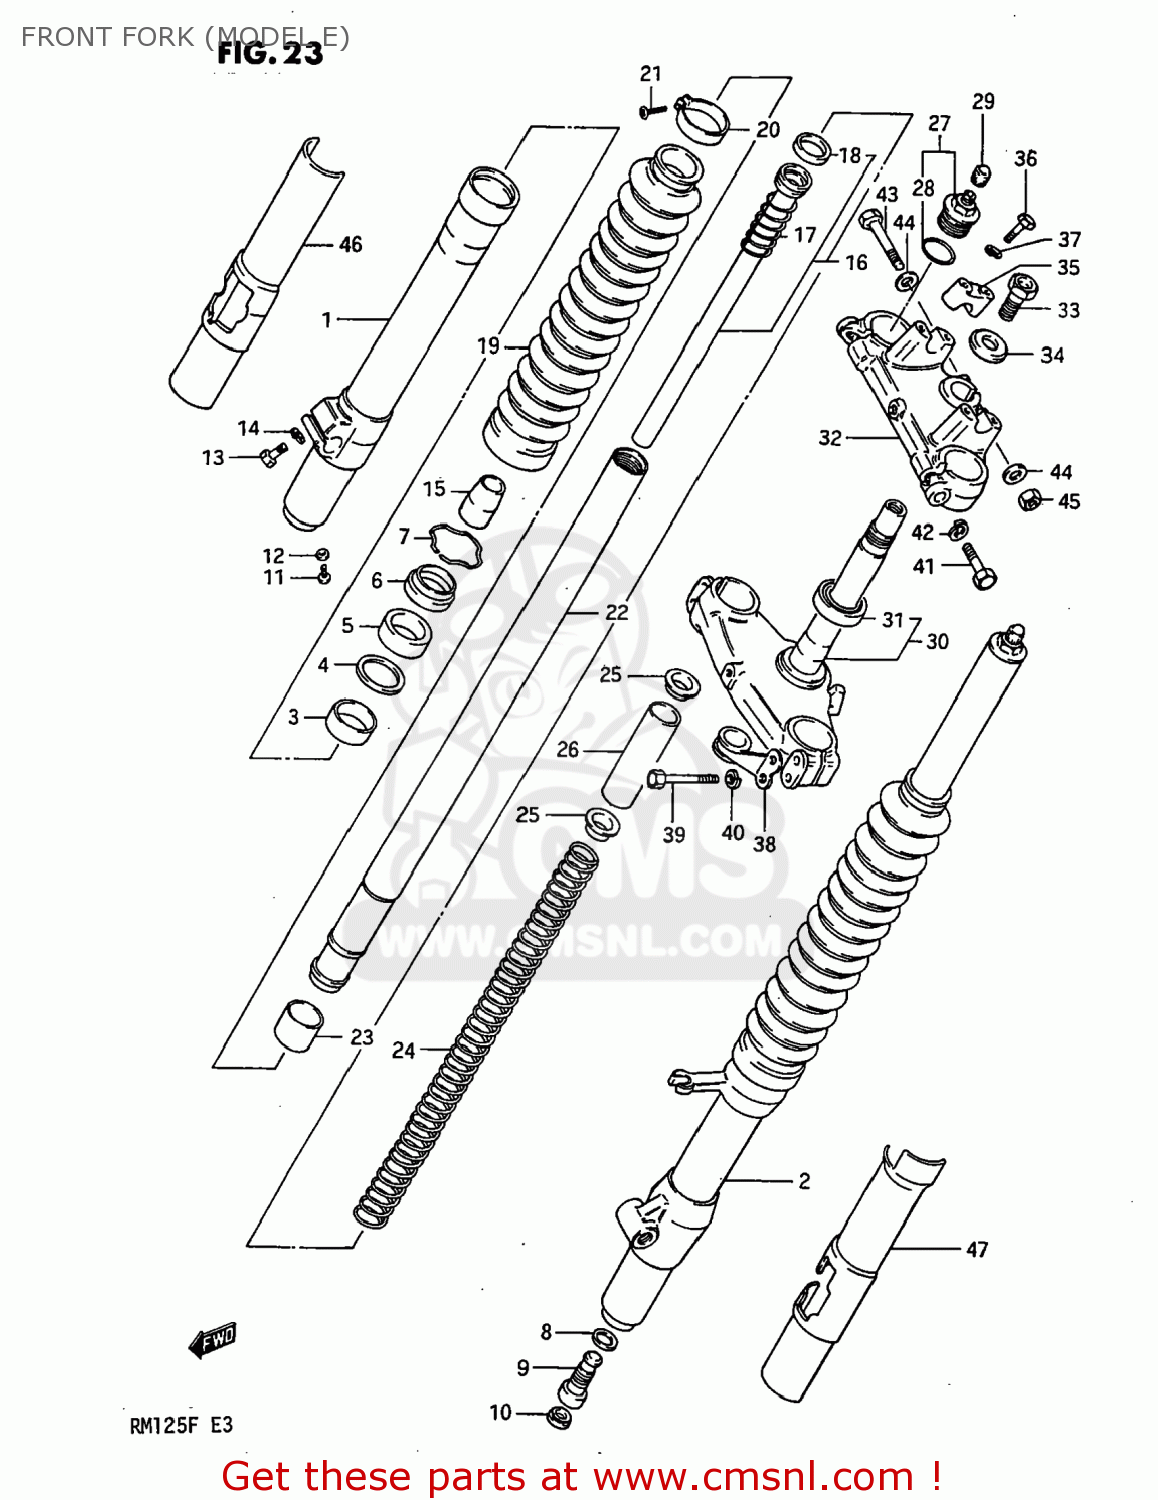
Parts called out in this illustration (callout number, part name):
1	TUBE,OUTER,RIGHT
2	TUBE,OUTER,LEFT
3	METAL,SLIDE
4	WASHER
5	SEAL,OIL
6	SEAL,DUST
7	RING,STOPPER
8	GASKET,FORK CYLINDER
9	VALVE,DF
10	CAP,FRONT FORK DF
11	SCREW 4X6
12	GASKET,DRAIN,PLUG (NAS)
13	BOLT (8X30)
14	WASHER,LOCK,8.
15	PIECE,FRONT FORK OIL LOCK
16	CYLINDER,FRONT FORK
17	SPRING,REBOUND
18	RING,FRONT FORK PISTON
19	BOOT,FRONT FORK COVER
20	BAND,BOOT,UPPER
21	SCREW 4X10
22	TUBE,FORK,INNER
23	PISTON
24	SPRING,FRONT FORK
25	GUIDE,FRONT FORK SPRING
26	SPACER,FRONT FORK SPRING
27	CAP,FORK INNER TUBE
28	O RING
29	CAP
30	STEM,STEERING
31	BEARING
32	HEAD,STEERING STEM
33	BOLT
34	WASHER
35	HOLDER,HANDLEBAR
36	BOLT
37	WASHER,LOCK,8.
38	GUIDE,CABLE
39	BOLT 8X40
40	WASHER,LOCK,8.
41	BOLT
42	LOCK WASHER
43	BOLT 8X50
44	WASHER
45	NUT
46	PROTECTOR,RIGHT
47	PROTECTOR
